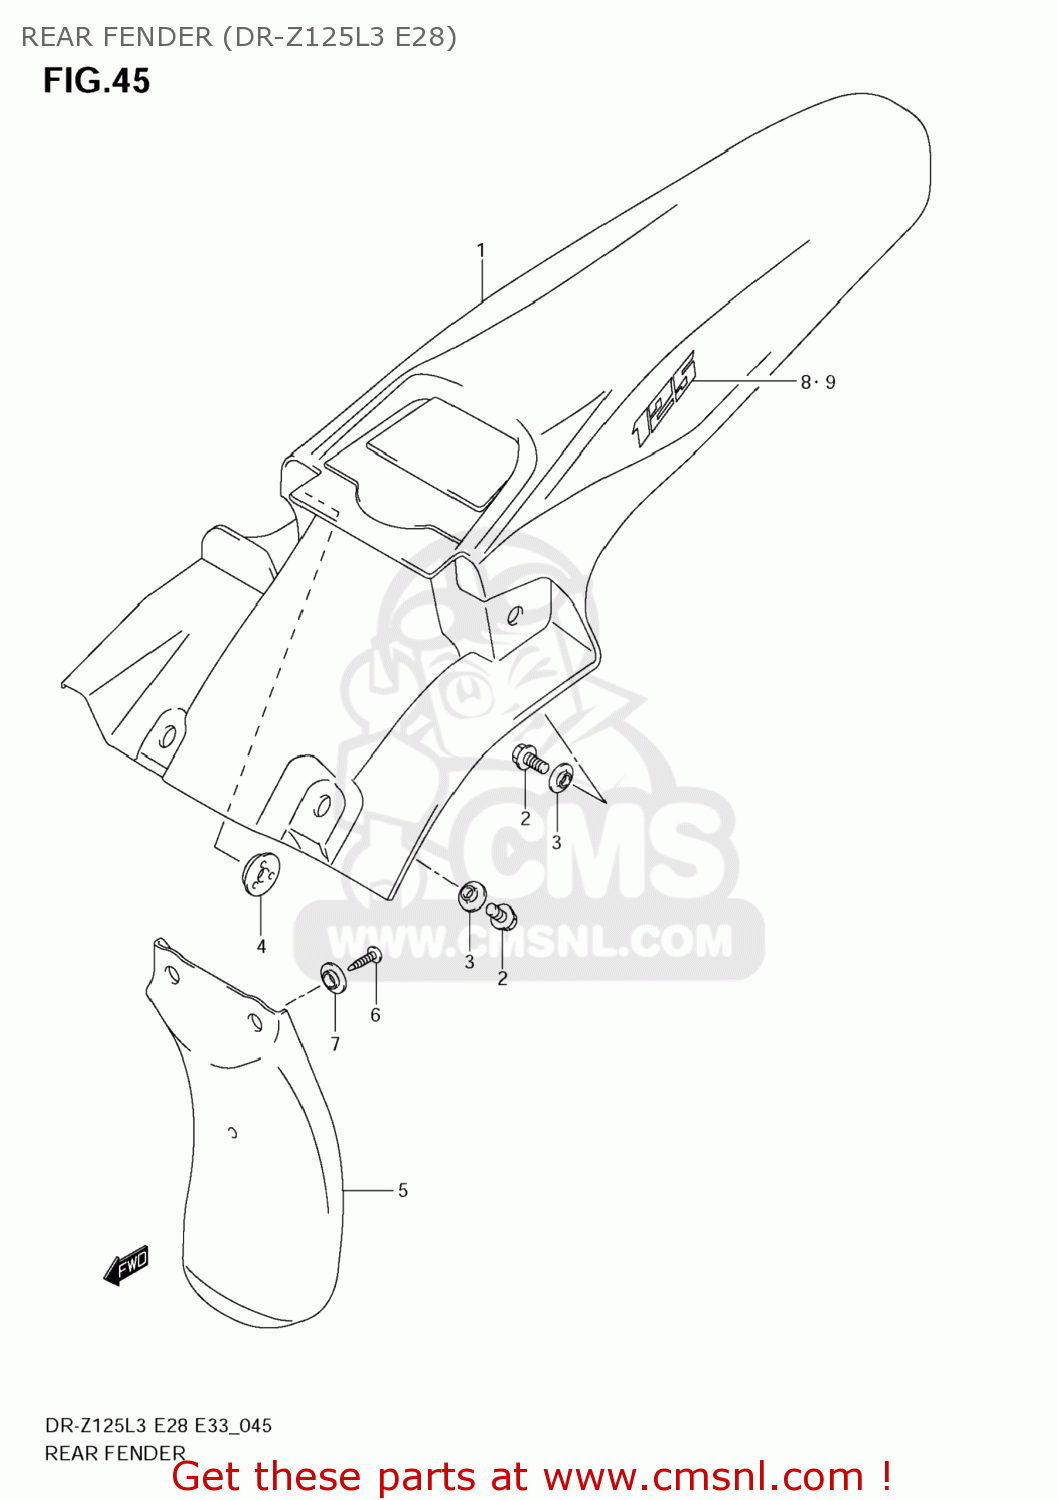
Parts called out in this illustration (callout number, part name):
1	FENDER,RR
2	BOLT(6X16)
3	WASHER
4	WASHER
5	MUDGUARD,RR FENDER FR
6	SCREW(5X16)
7	WASHER
8	EMBLEM,125,R
9	EMBLEM,125,L
